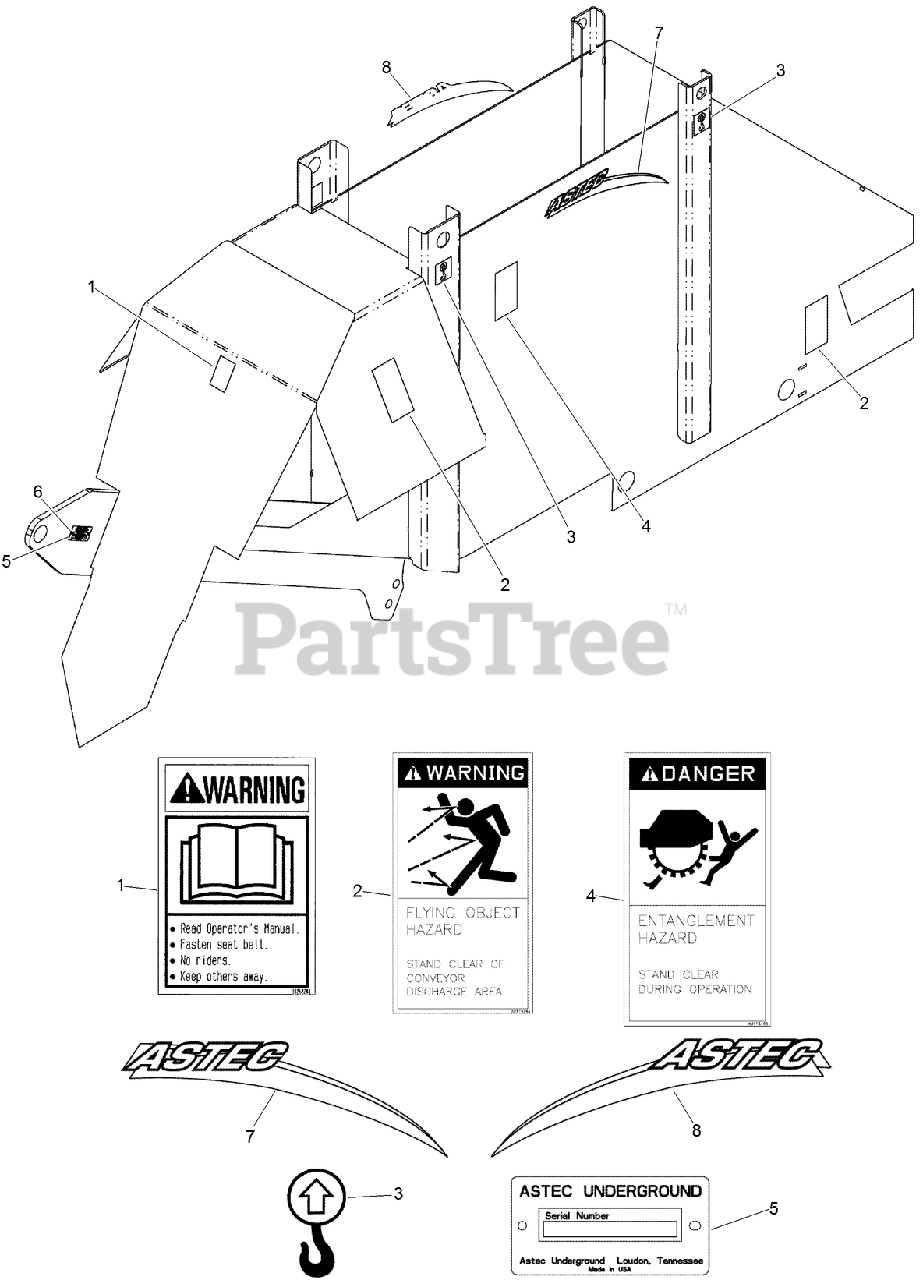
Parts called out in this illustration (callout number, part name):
1	DECAL - Warning, General Operation
2	DECAL - Wheel Hazard
3	DECAL - Lift Hook Location
4	DECAL - Danger, Tren Entangle Hazard
5	PLATE - Serial Number
6	TACK-FASTENER, STEEL
7	DECAL-Astec
8	DECAL-Astec
